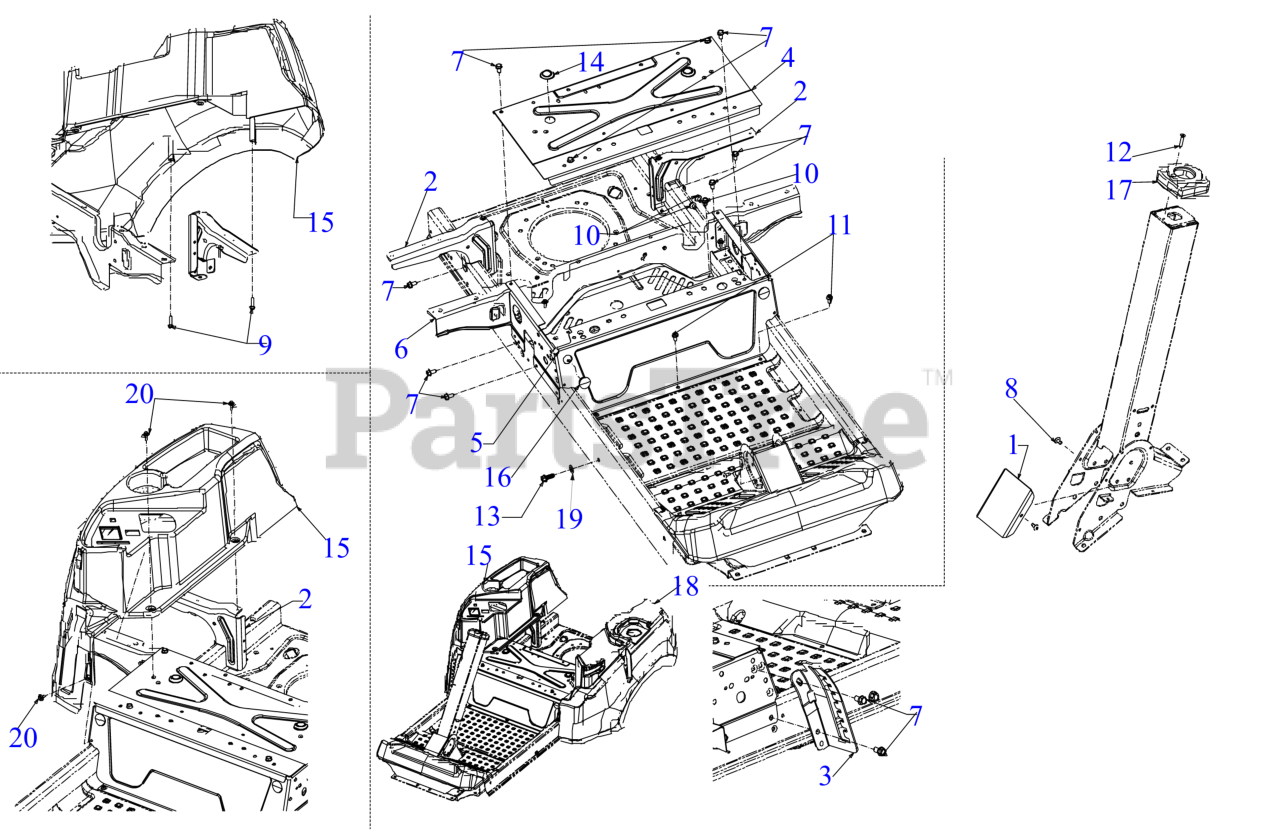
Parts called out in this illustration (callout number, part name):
2	REAR TANK BRACKET
3	HEIGHT INDEX BRACKET
7	SCREW 5/16-18 x .750
8	SCREW 1/4-20 x .5
9	SCREW 5/16-14 x 1
10	SCREW 5/16-18 x .500
11	SCREW 5/16-18 X.75
12	SCREW #10-16 x 1.25
13	SCREW 3/8-16 x 1.25 GR5
15	CONSOLE (RH)
16	PLASTIC PLUG
17	STEERING COLUMN COVER
18	CONSOLE (LH)
19	FLAT WASHER
20	SHOULDER SCREW M6-1 .368 X.115
